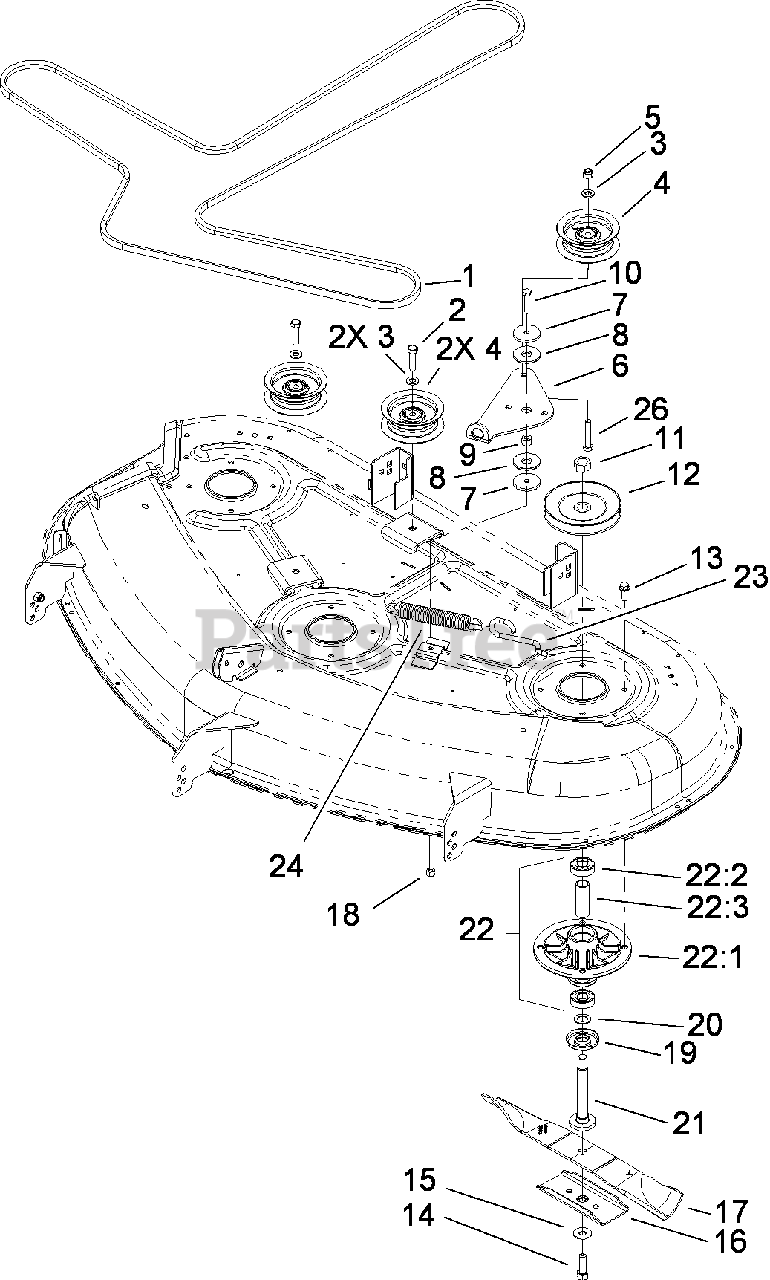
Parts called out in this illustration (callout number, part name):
2	SCREW-HH
3	WASHER-FLAT
4	PULLEY-IDLER, FLAT
5	NUT-LOCK, NI
6	ARM-IDLER
8	WASHER-FRICTION, COMPOSITE
10	SCREW-HH
11	NUT-HEX
12	PULLEY
13	SCREW-TAPTITE
14	SCREW-HH
15	WASHER-BELLEVILLE
16	STIFFENER-BLADE
17	BLADE-17.5 INCH, HIGH LIFT
18	NUT-LOCK, NI
19	SHIELD-BEARING
21	SHAFT-SPINDLE
22	Spindle ASM
22:1	HOUSING-SPINDLE
22:2	BEARING-BALL
23	HOOK-RETURN, SPRING
24	SPRING-EXTENSION
26	SCREW-HH
